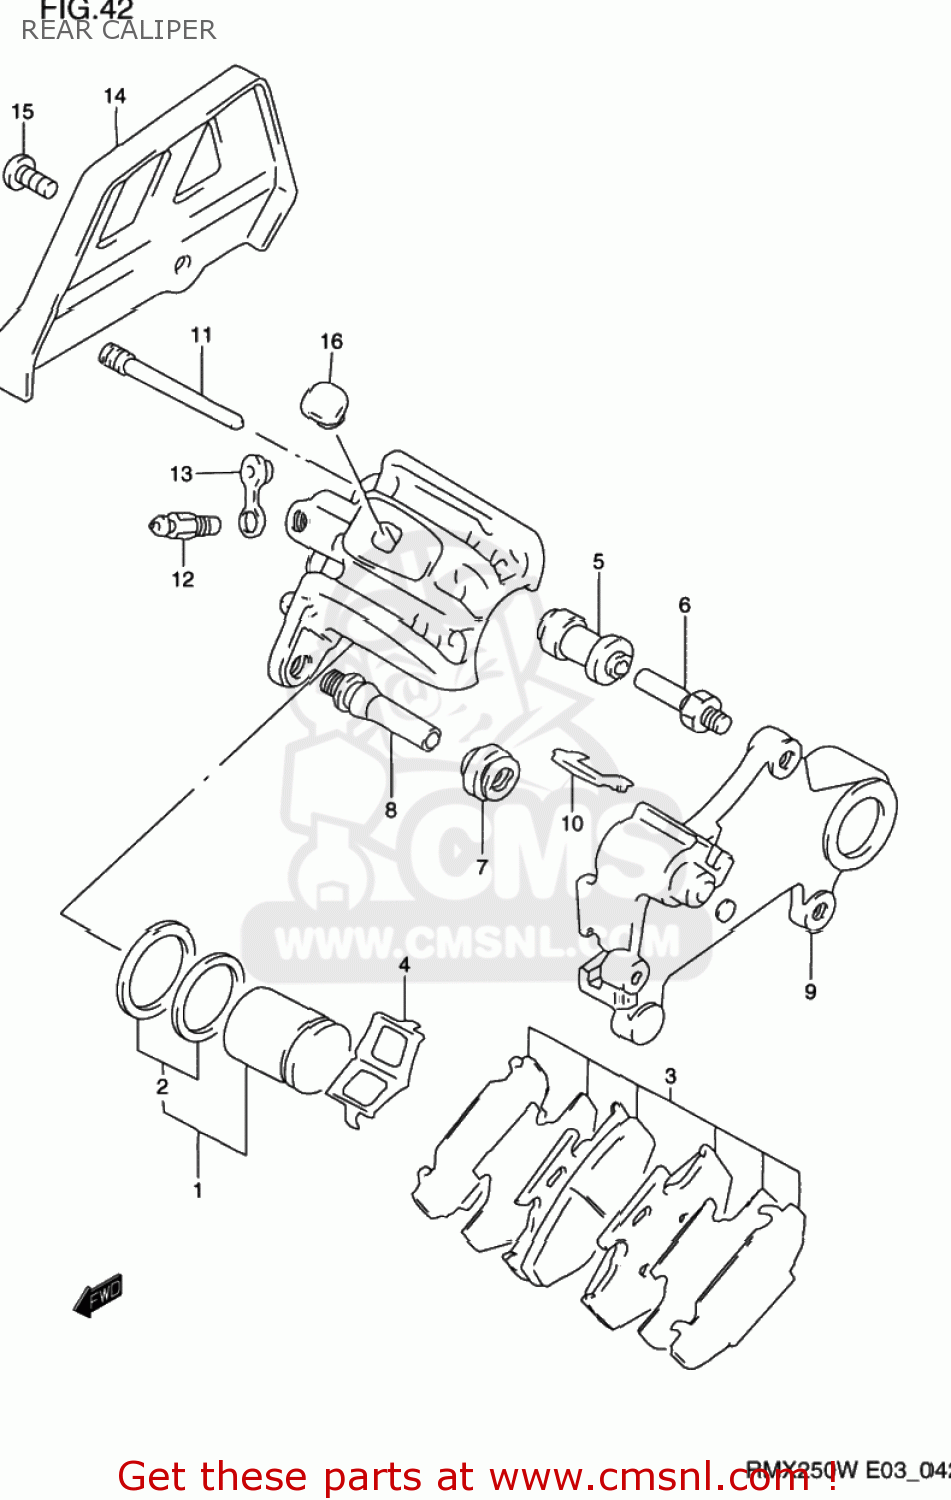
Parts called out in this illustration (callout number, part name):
1	PISTON SET
2	SEAL SET,PISTON
3	PAD & SHIM SET (NAS)
4	SPRING,PAD
5	BOOT
6	PIN,BOLT
7	BOOT
8	PIN
9	BRACKET
10	RETAINER,BRACKET
11	PIN,HANGER
12	BLEEDER
13	CAP,BLEEDER
14	GUARD SET,REAR CALIPER
15	SCREW 6X12
16	COVER,RR CALIPER BODY
